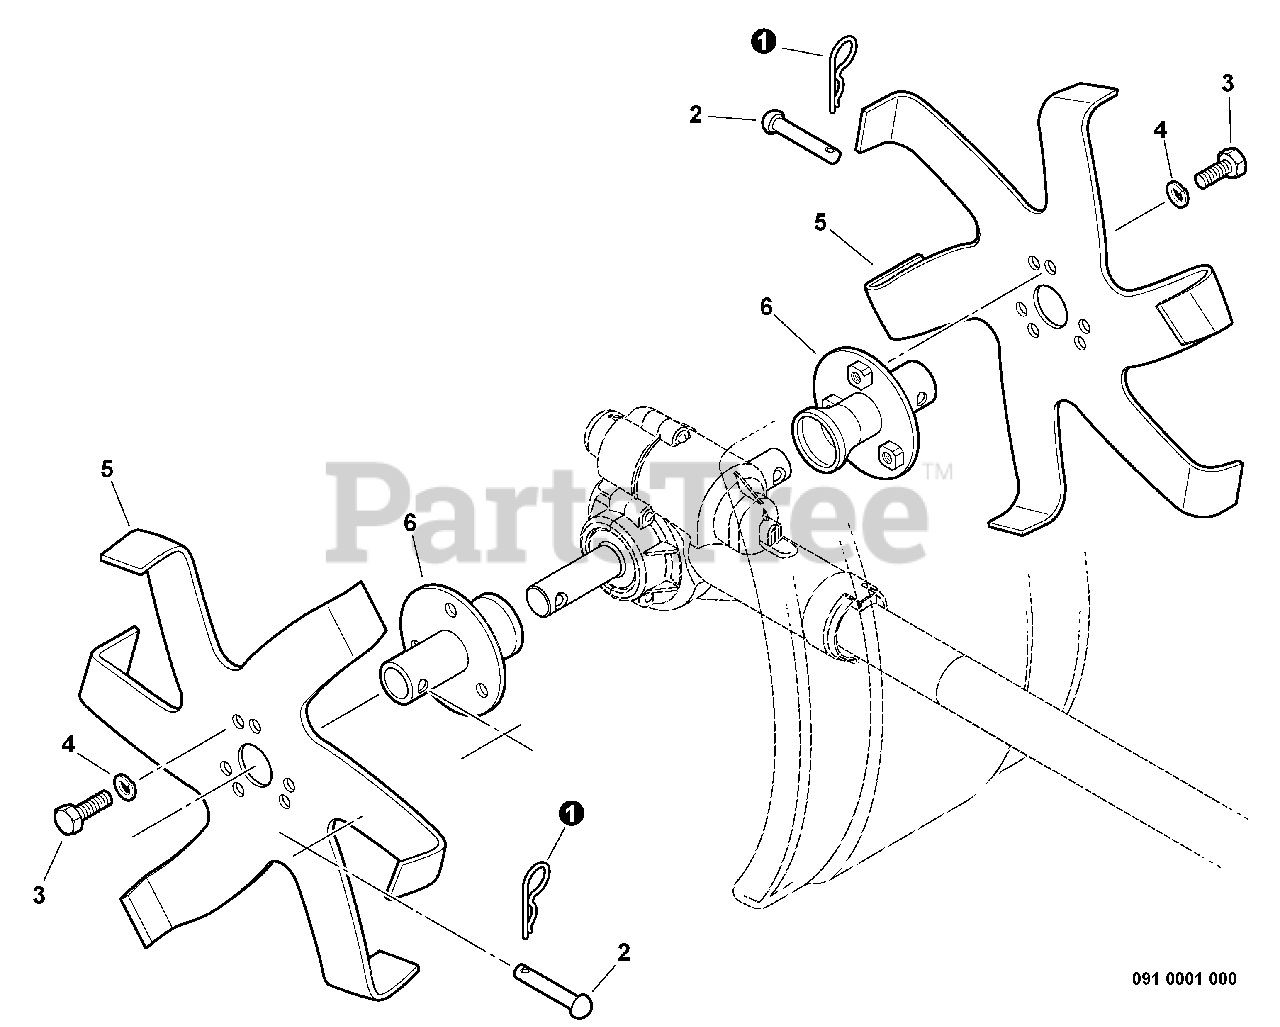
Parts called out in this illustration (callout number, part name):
1	PIN, COTTER 5
2	PIN, CLEVIS
3	BOLT 6×10
4	WASHER, SPRING 6
6	HUB, TINE
